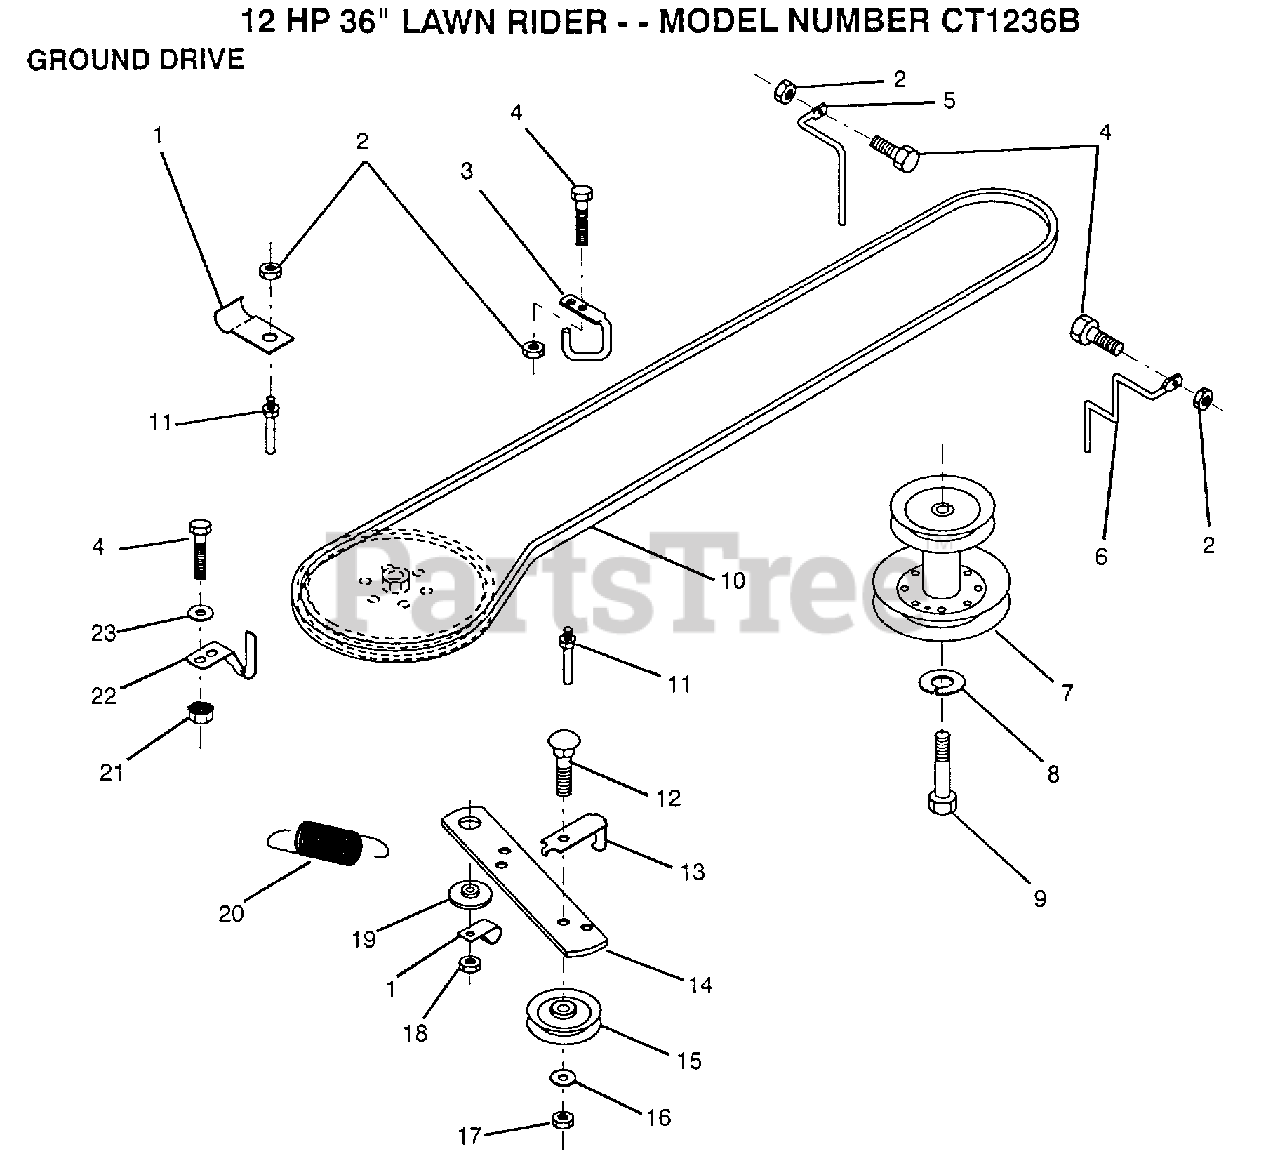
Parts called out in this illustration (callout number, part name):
1	"CLIP,INSULATOR"
3	"KEEPER,FRA DR BEL"
4	BOLT
5	KEEPER ENG BEL LH
6	KEEPER ENG DR RH
8	LOCKWASHER
9	BOLT
10	BELT
11	"KEEPER,DRIVE BELT"
12	BOLT
13	"KEEP,IDLER DR BEL"
15	PULLEY.IDLER.FLAT
16	WASHER
17	LOCKNUT
19	SPACER RETAINER
22	"KEEPER,DR BELT "
23	WASHER
